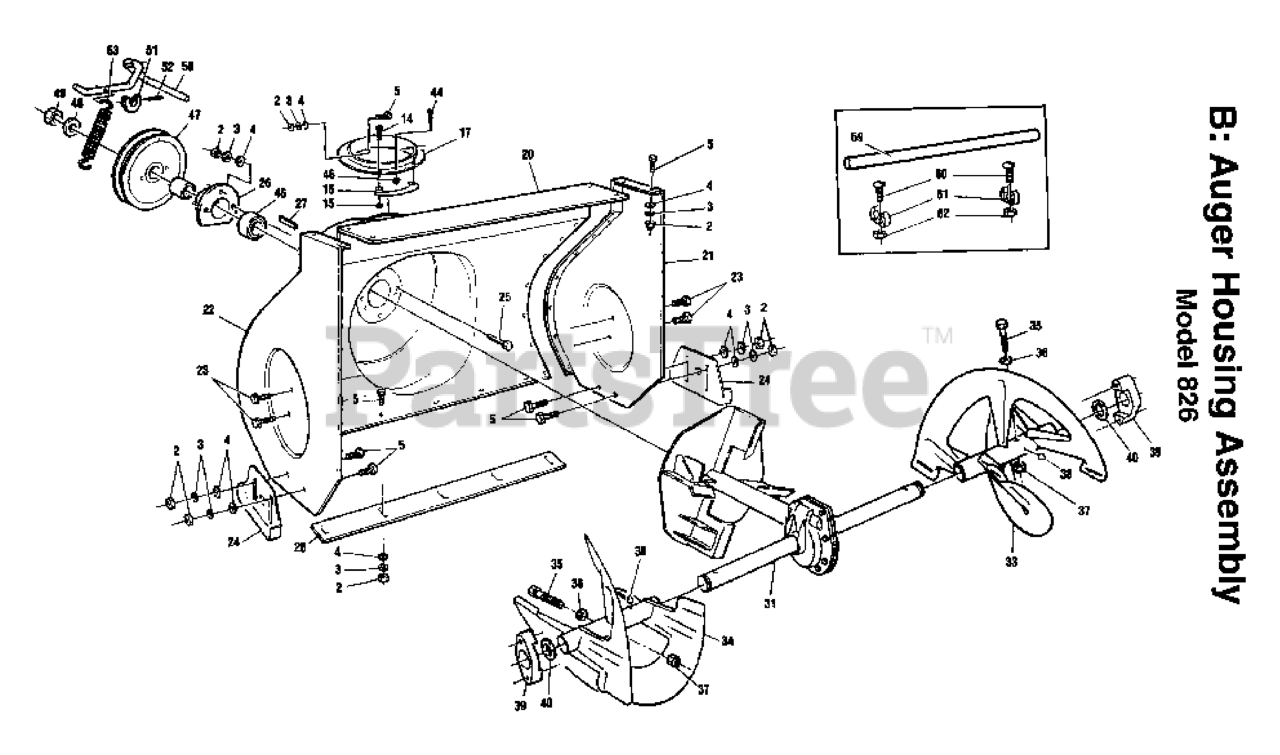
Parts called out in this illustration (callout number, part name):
2	LOCKNUT
3	WASHER.LOCK.HVY.HLCL.SPR.5/16
5	BOLT.CARR.SQNK.5/16-18UNC.X3/4
23	BOLT.FIN.HEX.5/16-18X3/4
37	NUT.CROWNLOCK.1/4
45	NUT.CROWNLOCK.1/4
